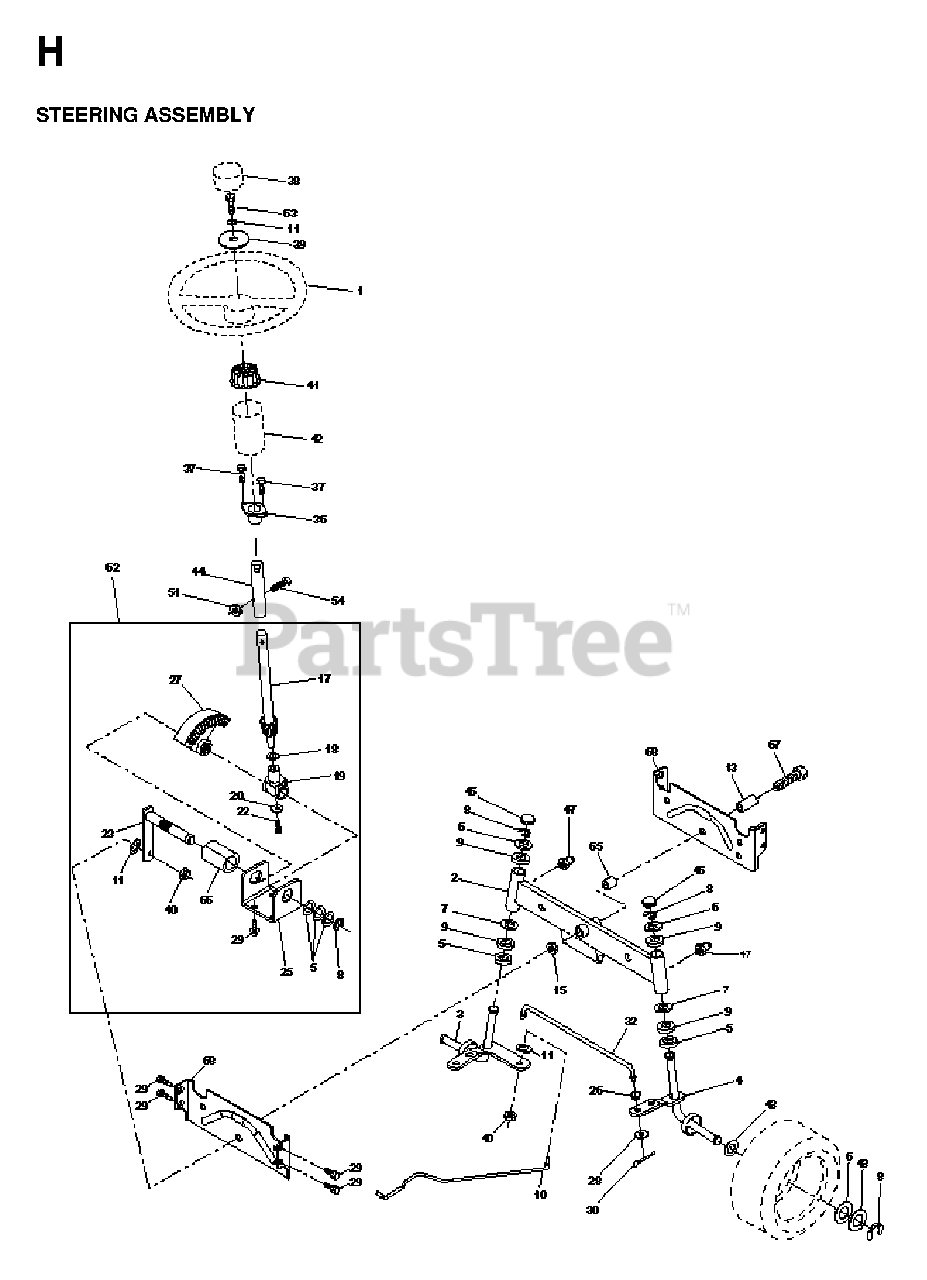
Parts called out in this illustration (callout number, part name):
2	AXLE ASSY
3	SPINDLE ASM LH
4	SPINDLE ASM RH
8	RING CLIP
9	BRNG T
10	DRAGLINK-STAMPED
11	WASHER, LOCK 3/8
13	BEARING AXLE
15	NUT-LOC,FLANGE LT
17	SHAFT ASM STEERING
18	THRUST WASHER
19	SHAFT,SUPPORT
20	WASHER
22	SCREW HEX SOCKET 1/4-20 X 5/8
23	SHAFT PITMAN
25	BRACKET STEERING
26	BUSHING.DRAGLINK
27	GEAR.SECTOR
28	WASHER
29	SCREW
30	COTTER PIN
32	TIE ROD
36	BUSHING, STEERING
38	RP INSERT
39	WASHER T
40	GRIPCO NUT
41	ADAPTER LT
42	STEERING BOOT, GRAY
44	EXT SHAFT STEERING
46	CAP.SPINDLE
47	ZERK M
51	NUT.71038.31-18.HEX.NYLOCK
54	BOLT.5/16-18X1-1/4 FULL.THREAD
62	KIT, STEERING ASSEMBLY
65	SPACER AXLE
66	BEARING ARM
67	BOLT.HEX.FINISHED.5/8
68	AXLE, BRACE
